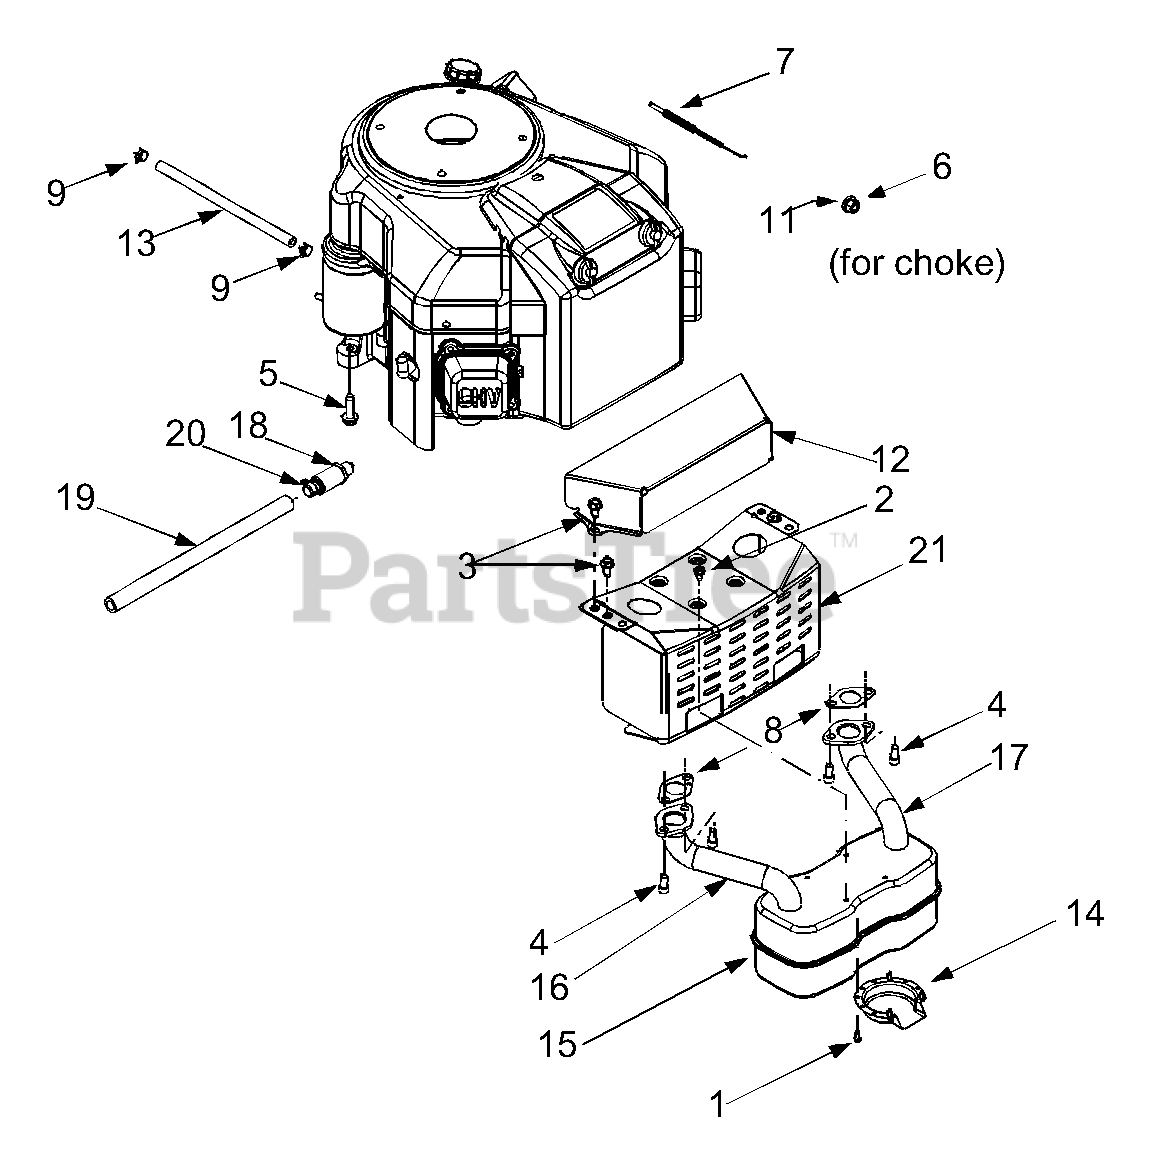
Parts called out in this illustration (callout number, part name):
1	Screw, #8-18 x .5
2	Self-tapping Screw, 1/4-20 x .5
3	Self-tapping Screw, 5/16-12 x .75
4	Socket Cap Screw, 5/16-18 x .625
5	Self-tapping Screw, 3/8-16 x 1.25
6	Hex Nut, 3/8-16
7	Throttle Cable
8	Exhaust Gasket
11	Lock Washer, .406 x .875 x .059
12	Engine Heat Shield
13	Fuel Line Hose
14	Muffler Deflector
15	Muffler, Twin Inlet
16	RH Exhaust Pipe
17	LH Exhaust Pipe
18	Oil Drain Valve
19	Oil Drain Hose
20	Oil Drain Cap
